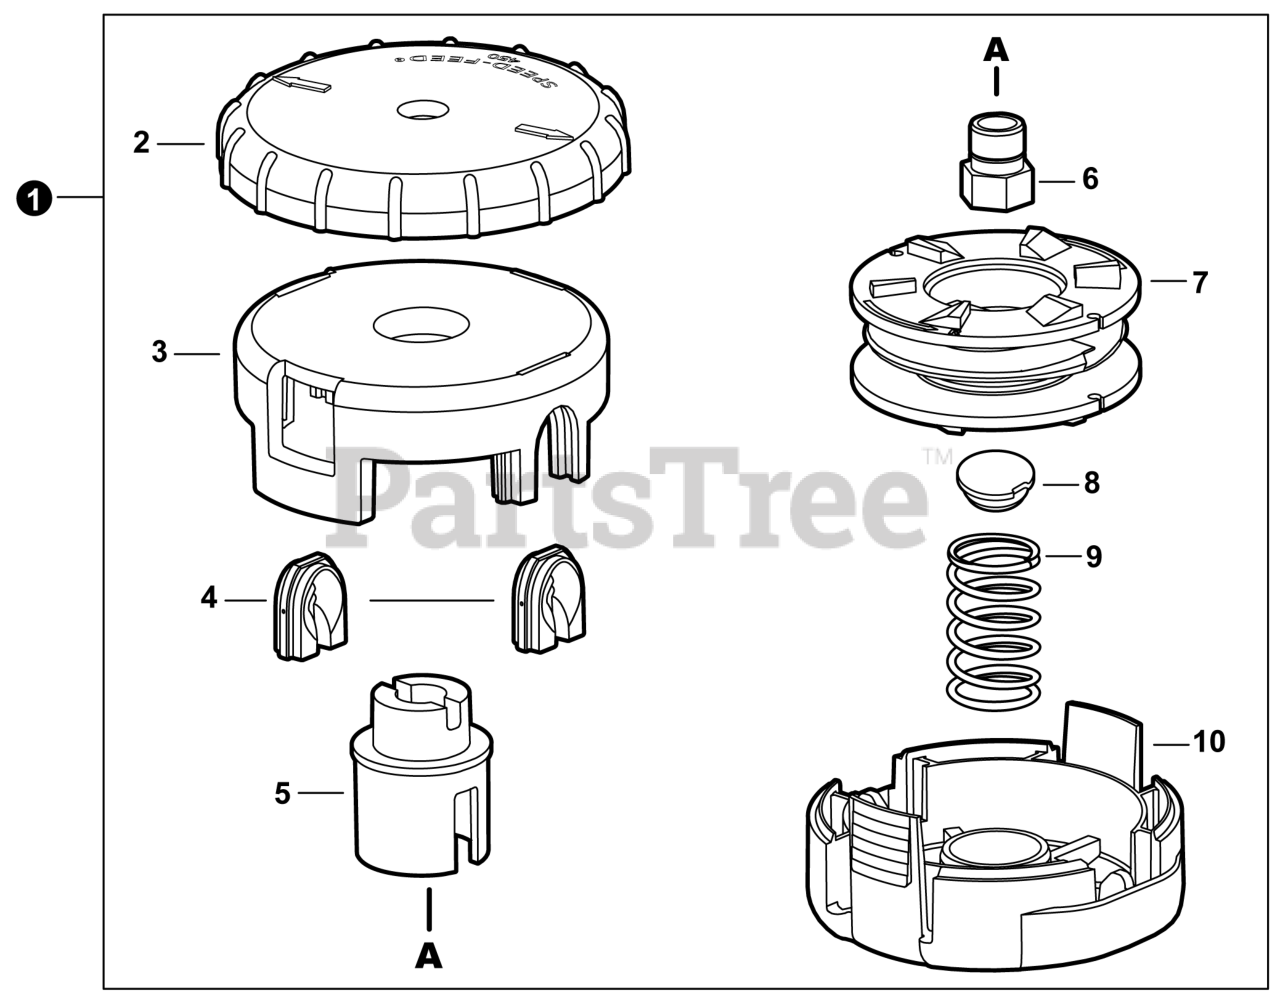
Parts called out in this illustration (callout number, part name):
1	TRIMMER HEAD, SPEED-FEED® 450
3	HOUSING, SPOOL
5	HUB, SPOOL
6	BUSHING M10×1.25 LH GOLD
7	SPOOL LH
8	CAP, SPRING
9	SPRING, GOLD
10	COVER, SPOOL
